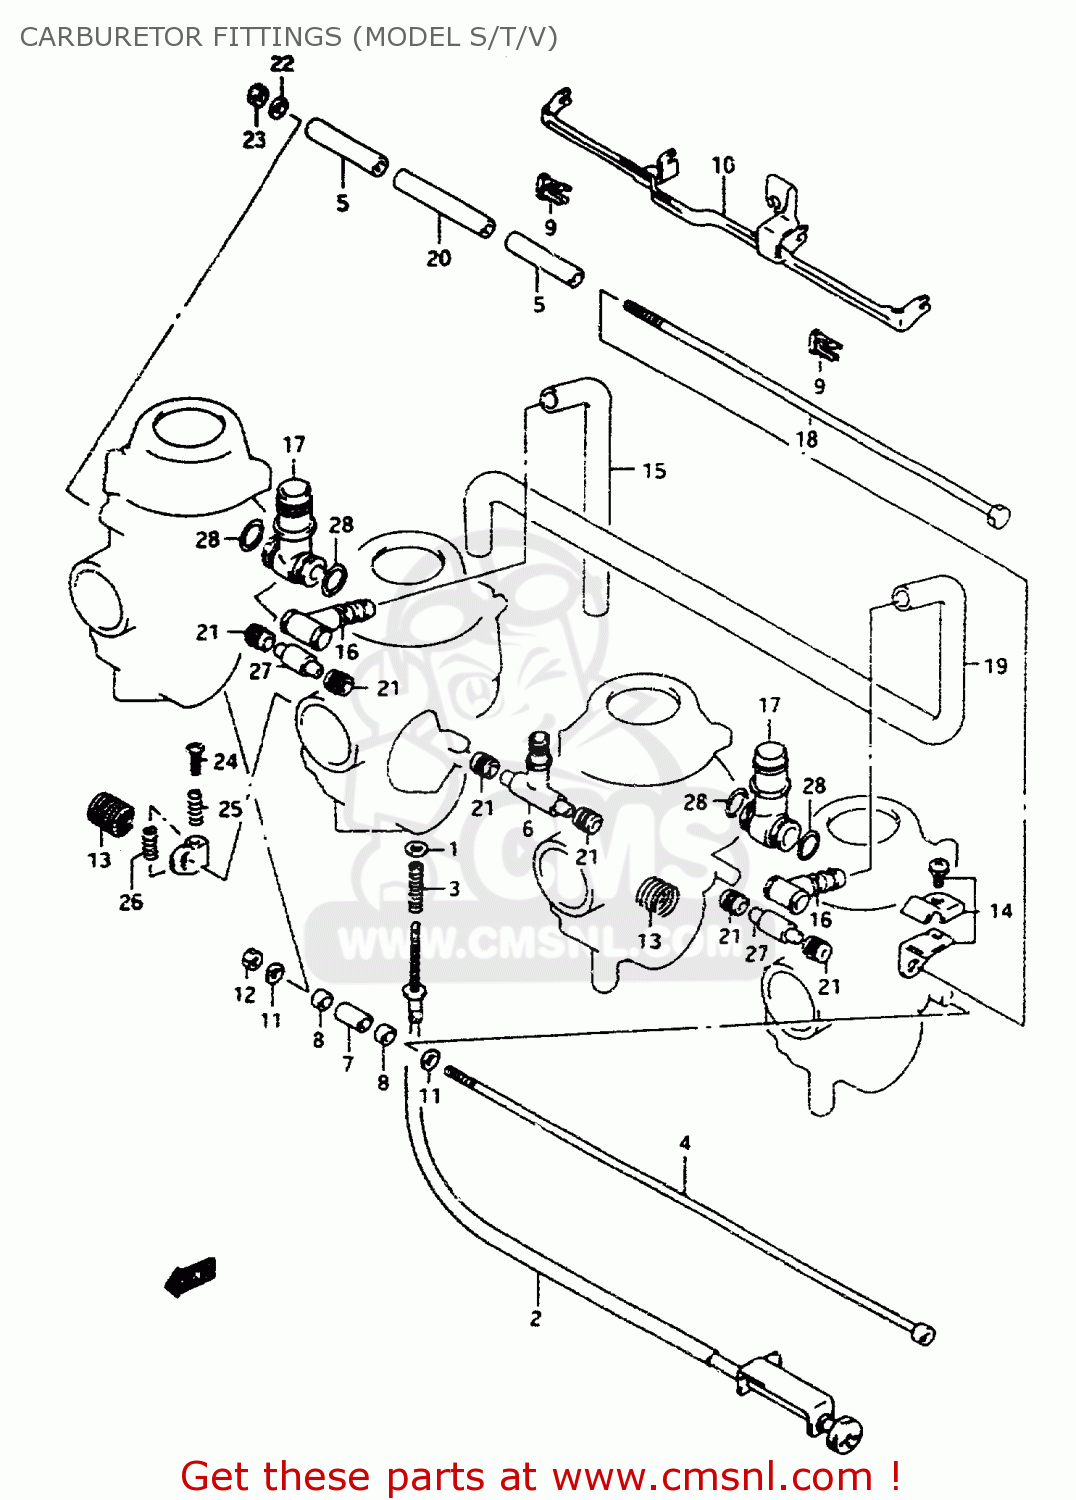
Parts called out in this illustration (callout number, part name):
1	WASHER
2	SCREW,ADJUST
3	SPRING
4	BOLT
5	RING
6	NIPPLE
7	RING
8	RING
9	HOLDER
10	LEVER,STARTER
11	WASHER
12	NUT
13	SPRING
14	BRACKET ASSY
15	HOSE
16	3 WAY
17	NIPPLE
18	BOLT
19	HOSE
20	RING
21	SEAL
22	WASHER
23	NUT 6MM
24	SCREW
25	SPRING
26	SPRING,THROTTLE SCREW
27	PIPE
28	PIPE
29	O-RING
